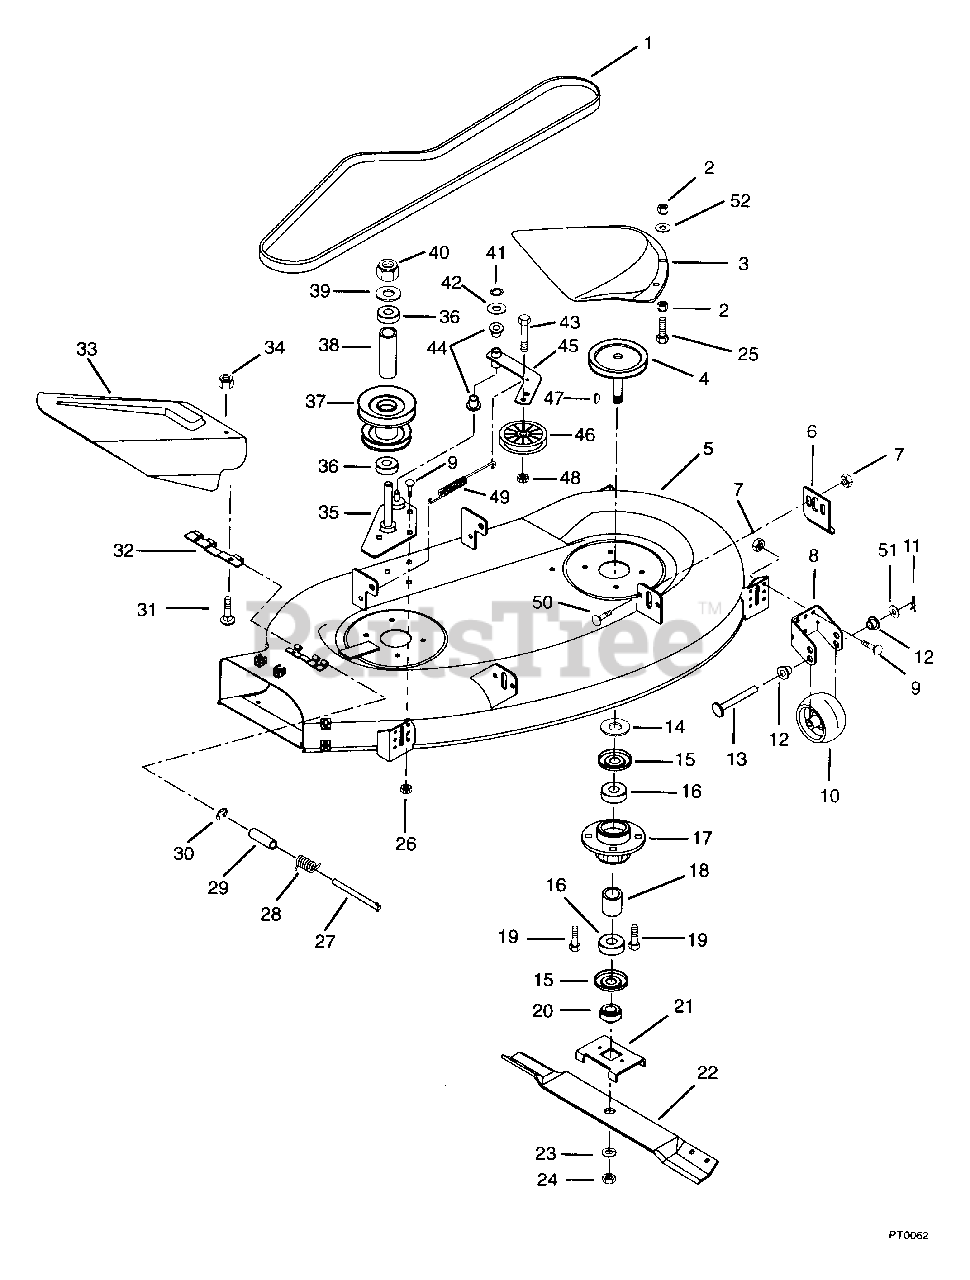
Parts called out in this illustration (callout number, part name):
1	V-BELT, 4L-WRAPPED
2	NUT-LK-CTR .375-16 GR A PL
4	L. SPINDLE SHEAVE
4	R. SPINDLE SHEAVE
5	40" MOWER DECK W/DECALS
5	40" MOWER DECK ASSY COMPLETE
6	MOWER ADJUSTMENT TAB
7	NUT-FLG. .312-18 PL
8	ROLLER CLEVIS
9	BLT-RDHDSQNK .312-18X.62SHTPL
11	PIN-HAIR INT .08X.18X1.18
12	BSHG-FLG .372X.500X.312X.625NY
13	PIN-CLEV .371X3.25 YWZC
14	WSHR-FL-STL .755X1.250X.125
15	BEARING SLINGER
16	BRG-BALL .750X1.781X.61
17	SPINDLE HOUSING
18	SPACER .753X1.000X1.140
19	BLT-RDHDSQNK .38-16X1.0 GR5PL
20	RETAINER HUB
21	BLADE TRAY 48
23	WSHR-LK .750X.188 MED PL
24	NUT-JAM .75-10 PL
25	BLT-HEX .38-16X1.00 PL GR5
26	NUT-FLG. .312-18 PL
28	SG-TORS .095X.50X 1.0
29	BSHG-SLV .334 X .502 X 1.437
30	RG-RTNG-EXT .312X.025
31	BLT-RDHDSQNK .25-20X.50 SHT PL
32	HINGE PLATE
33	40IN. CHUTE DEFLECTOR
34	NUT-LK-FLG .250-20 PL
35	MOUNT PLATE 40"
36	BRG-BALL .625X1.375X.44
37	JACKSHAFT PULLEY
38	SPACER .640X.880X2.545
39	WSHR-FL-STL .640X1.005X.062 PL
40	NUT-LK-NYL.625-18 PL
41	RG-RTNG-EXT .500X.042 (E)
42	WSHR-FL-STL .505X.880X.072 PL
43	BLT-HEX .38-16X1.50 PL GR5
44	BSHG-FLG.500X.625X.312X.750NY
45	IDLER ARM
46	IDLER-FLAT 3.00X.38
47	KEY-WDRF .188X.625X.31 SAE9MOD
48	NUT-LK TOP .375-16 GR C YWZC
49	SG-TENS .113X.812X7.00
50	BLT-RDHDSQNK.31-18X.75GR5SHTPL
51	WSHR-PLASTIC .390X.875X.062
52	WSHR-FL-STL.406X.812X.065PL
